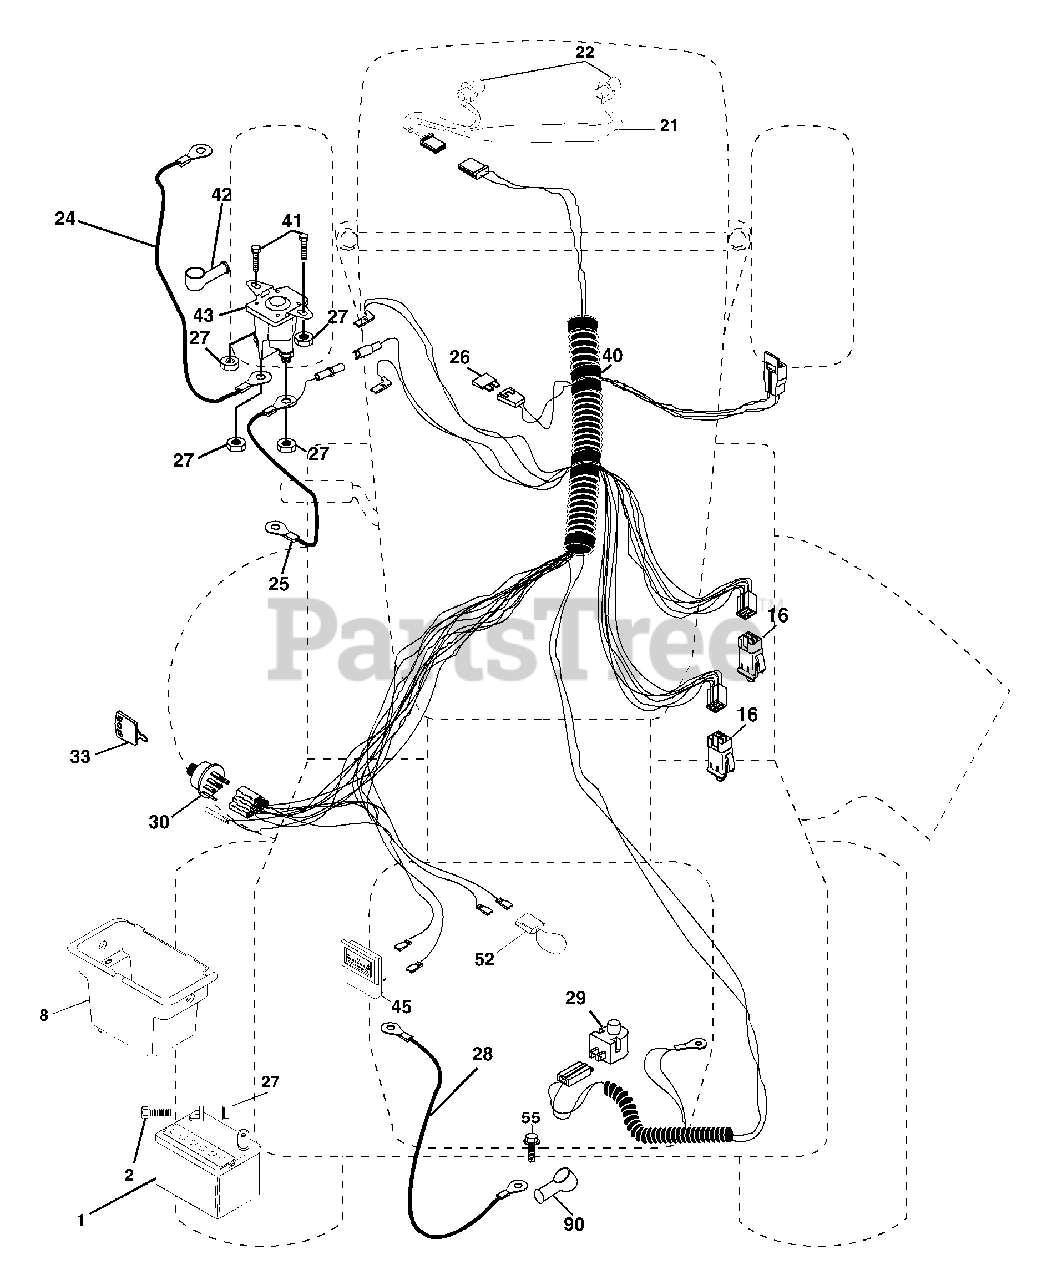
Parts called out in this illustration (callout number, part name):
1	Battery
2	Bolt Hex Hd 1/4-20unc X 3/4
8	Battery Box
16	Switch Interlock Push-In
21	Harness Socket Light
22	Bulb, Light # 1156
24	Cable Battery
25	Cable Battery 6 Ga Red w/16 wire
26	Fuse
27	Nut Keps Hex 1/4-20 Unc
28	Cable Ground 6ga 12 black
29	Switch Plunger Nc Gray
30	Switch Ign
33	Key Ign Molded Generic
40	Harness Ign
41	Bolt Fin Hex 1/4-20uncx 1/2
42	Cover Terminal Red
43	Solenoid
45	Ammeter Rectangular
52	Protection Loop
90	Cover Terminal
